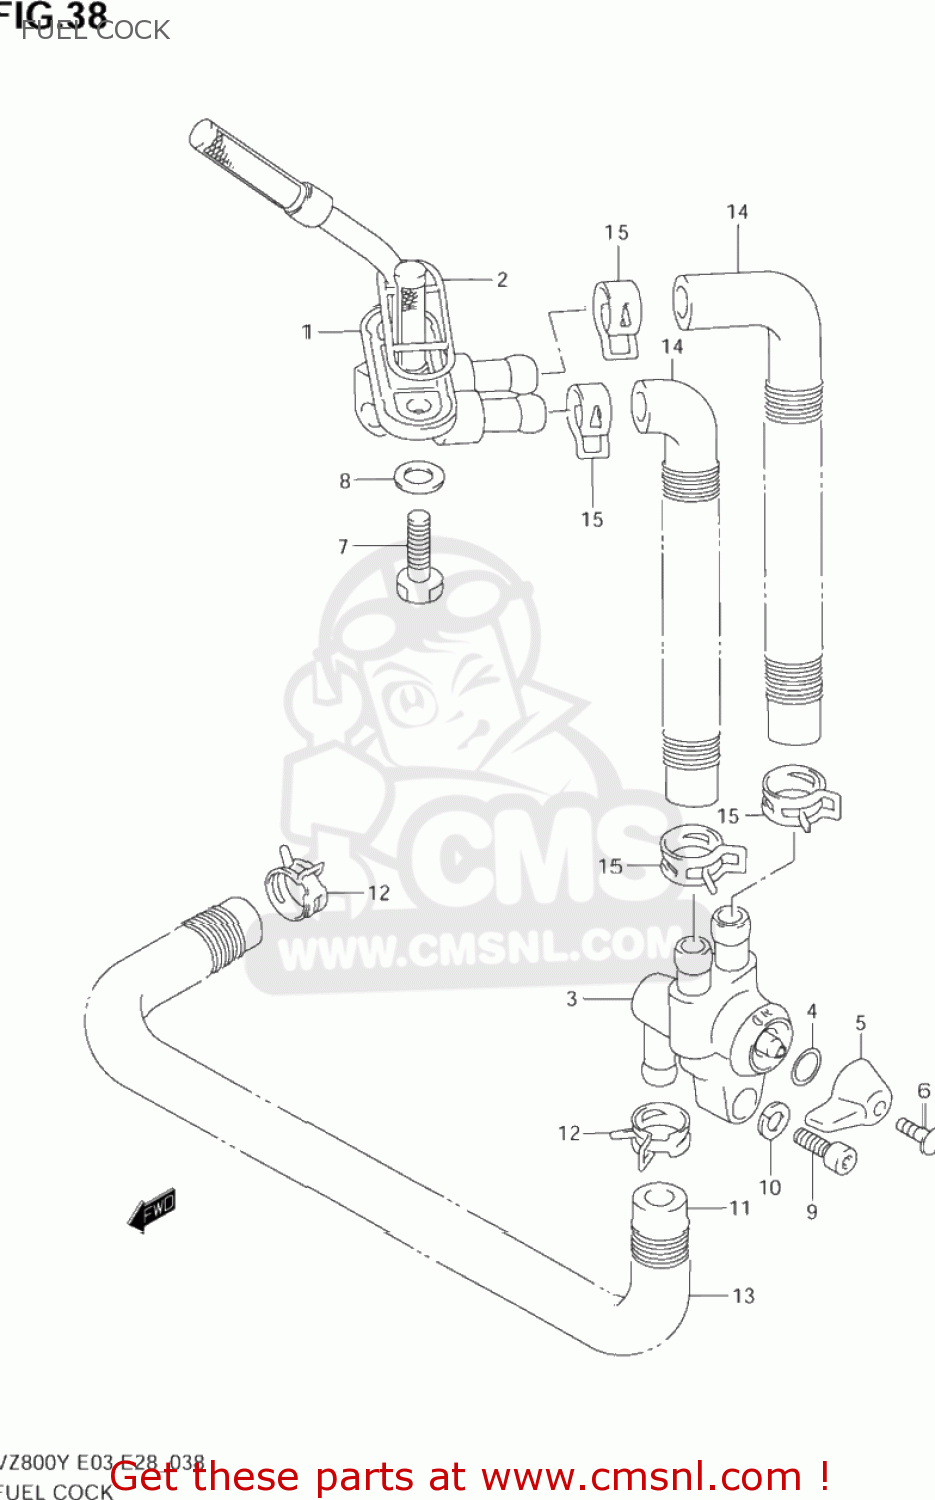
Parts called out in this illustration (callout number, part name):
1	FILTER UNIT,FUEL
2	GASKET,JOINT (NAS)
3	COCK ASSY,FUEL
4	O RING,LEVER
5	LEVER,FUEL COCK
6	SCREW,COCK LEVER
7	BOLT(6X20)
8	GASKET(6.4X11.5X0.8) (NAS)
9	BOLT
10	LOCK,WASHER
11	HOSE,FUEL
12	CLIP
13	SPRING
14	HOSE,FUEL FILTER/COCK
15	CLIP
